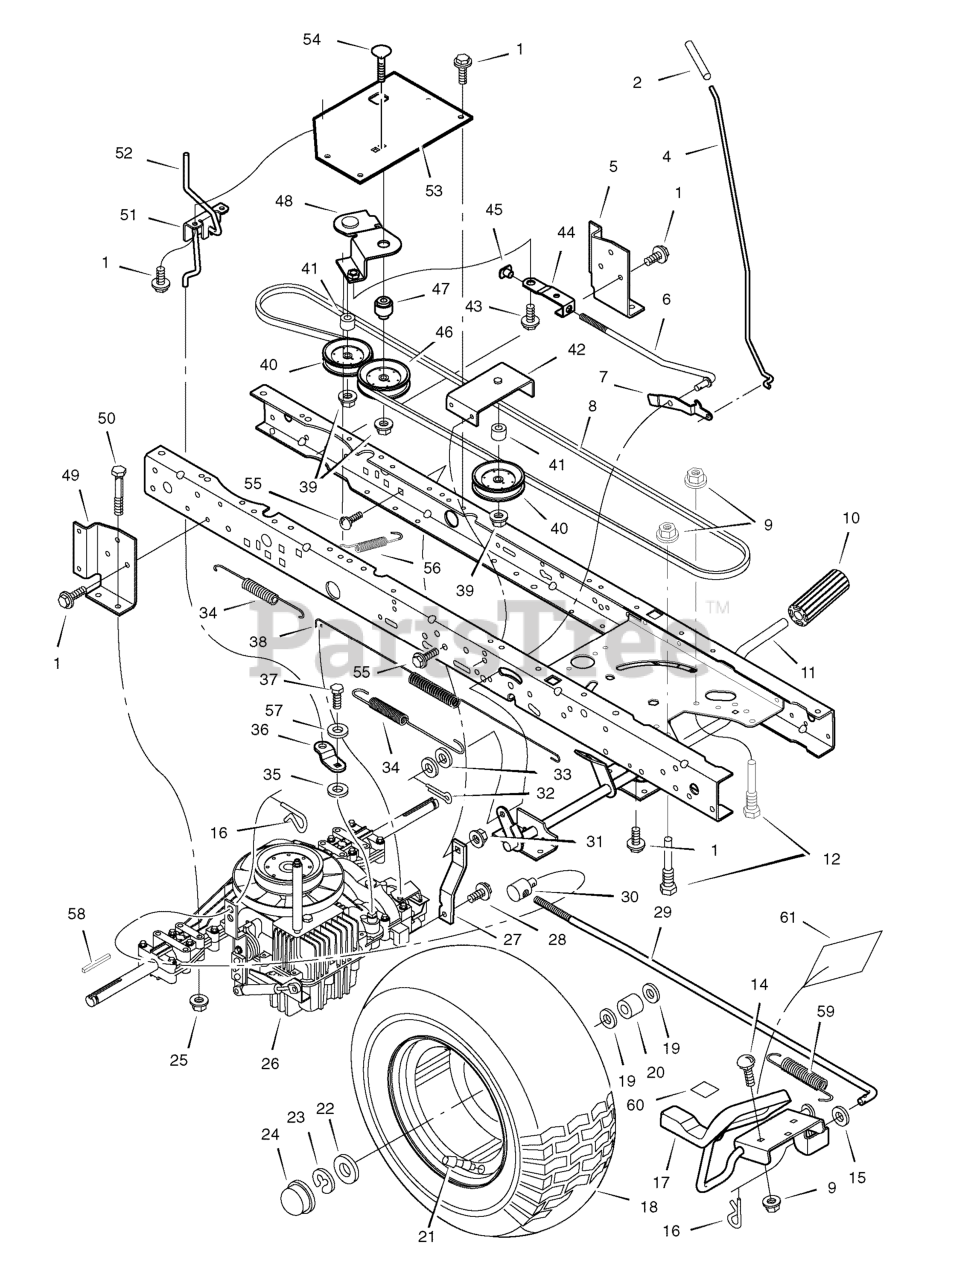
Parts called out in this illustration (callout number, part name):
2	GRIP, Parking Brake
4	ROD, Parking Brake
5	BRACKET, Left Transaxle
6	ROD, Clutch
7	LATCH, Parking Brake
8	V-BELT, Drive
9	NUT, Flange
10	PEDAL, Brake/Clutch
11	BRAKE PEDAL ASSEMBLY
12	SCREW, Guide
14	BOLT, Carriage
16	PIN, Hair
17	PEDAL ASSEMBLY, Hydro
18	WHEEL & TIRE ASSEMBLY, Rear
21	STEM, Valve
24	CAP, Hub
25	NUT, Centerlock
26	Transaxle, Peerless Hydro **
27	Strap, Torque **
29	ROD, Control
30	NUT, Adjusting
31	NUT, Centerlock
32	PIN, Cotter
34	SPRING, Extension
36	ARM, Disconnect
38	SPRING, Brake
39	LOCKNUT, Flange
40	PULLEY, Idler
42	BRACKET, Idler Assembly
43	BOLT, Shoulder
44	LINK, Clutch
45	NUT, Tee
46	PULLEY, Idler
47	BUSHING, Pivot
48	ARM ASSEMBLY, Idler
49	BRACKET, Right Transaxle
50	BOLT, Hex
51	BRACKET, Dump Valve
52	ROD, Roll Release
53	BRACKET, Idler Pivot
54	BOLT, Carriage
55	BOLT, Carriage
56	SPRING, Clutch
58	KEY, Square 3/16"
59	SPRING, Extension
60	MAT, Toe Reverse
61	PAD, Hydro Pedal
